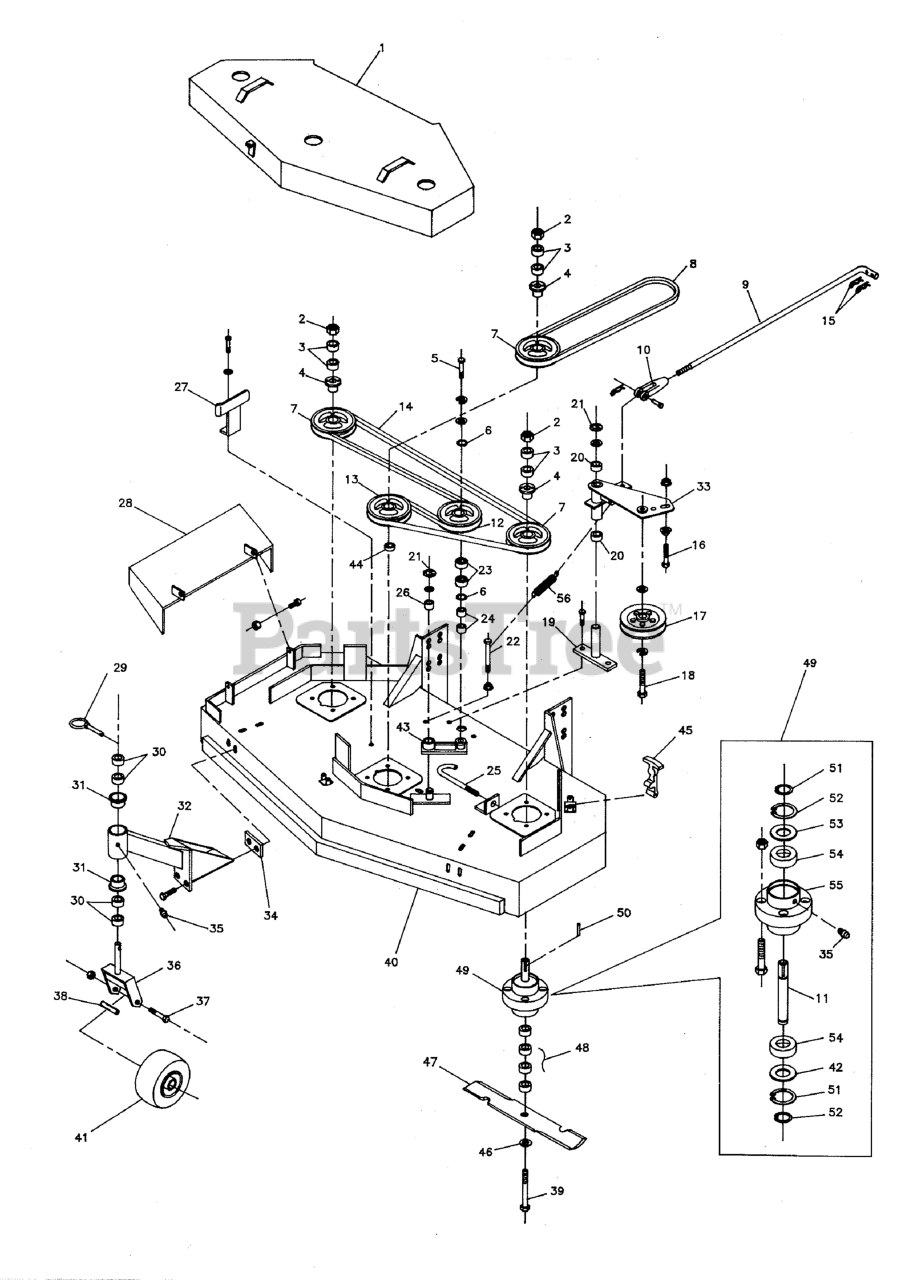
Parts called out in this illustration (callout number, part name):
1	48" Guard
2	NUT, 5/8-11 Hex
3	SPACER, .63 x 1.06 x .23
4	BUSHING, Tapered Hub
5	BOLT, 1/2-20 X 1-3/4" GD8 CZ
6	SNAP RING, Internal
7	PULLEY, Spindle
9	Blade Engagement Rod
10	CLEVIS, 3/8-24, Plastic
11	SPINDLE SHAFT
12	PULLEY, Idler
13	SPINDLE PULLEY
14	BELT, Blade Spindle
15	HAIRPIN CLIP
16	BOLT, 5/16-18 x 1-3/4
17	Idler Pulley
18	BOLT, 1/2-20 X 1-1/2, GD5 CZ
19	Idler Mount
20	BUSHING, Brass
21	C-CLIP
22	BOLT, 5/16-18 x 3
23	BEARING, BALL 11/16X1-9/16X15/32
24	INSERT, Bearing
26	BUSHING, Brass
27	Belt Guide
28	CHUTE, DISCHARGE WELDMENT
29	PIN, Lynch
30	SPACER, 1.02 x 1.56 x .50
31	BUSHING, Flange
32	Caster Support
33	Blade Engagement Pivot
34	Caster Mount Spacer
35	GREASE FITTING
36	YOKE, Caster
37	BOLT, 1/2-13 x 5-1/2
38	AXLE, Caster Wheel
39	BOLT, 5/8-11 x 9-1/2
40	48" MOWER HOUSING
41	TIRE ASSM, Solid Rubber, 9 X 3.5
42	SPINDLE WASHER, Bottom
43	IDLER ARM
44	SPACER, 1.00 X 1.25 X .25
45	RUBBER LATCH
46	WASHER, 5/8" USS
47	MOWER BLADE, 16-1/4"
48	SPACER, .63 x 1.06 x .23
49	SPINDLE ASSEMBLY, Complete
50	KEY, 1/4 SQ. X 2-1/2
51	SNAP RING, External
52	SNAP RING, Internal
53	SPINDLE WASHER, Top
54	BEARING
55	SPINDLE HOUSING
56	SPRING, Extension
